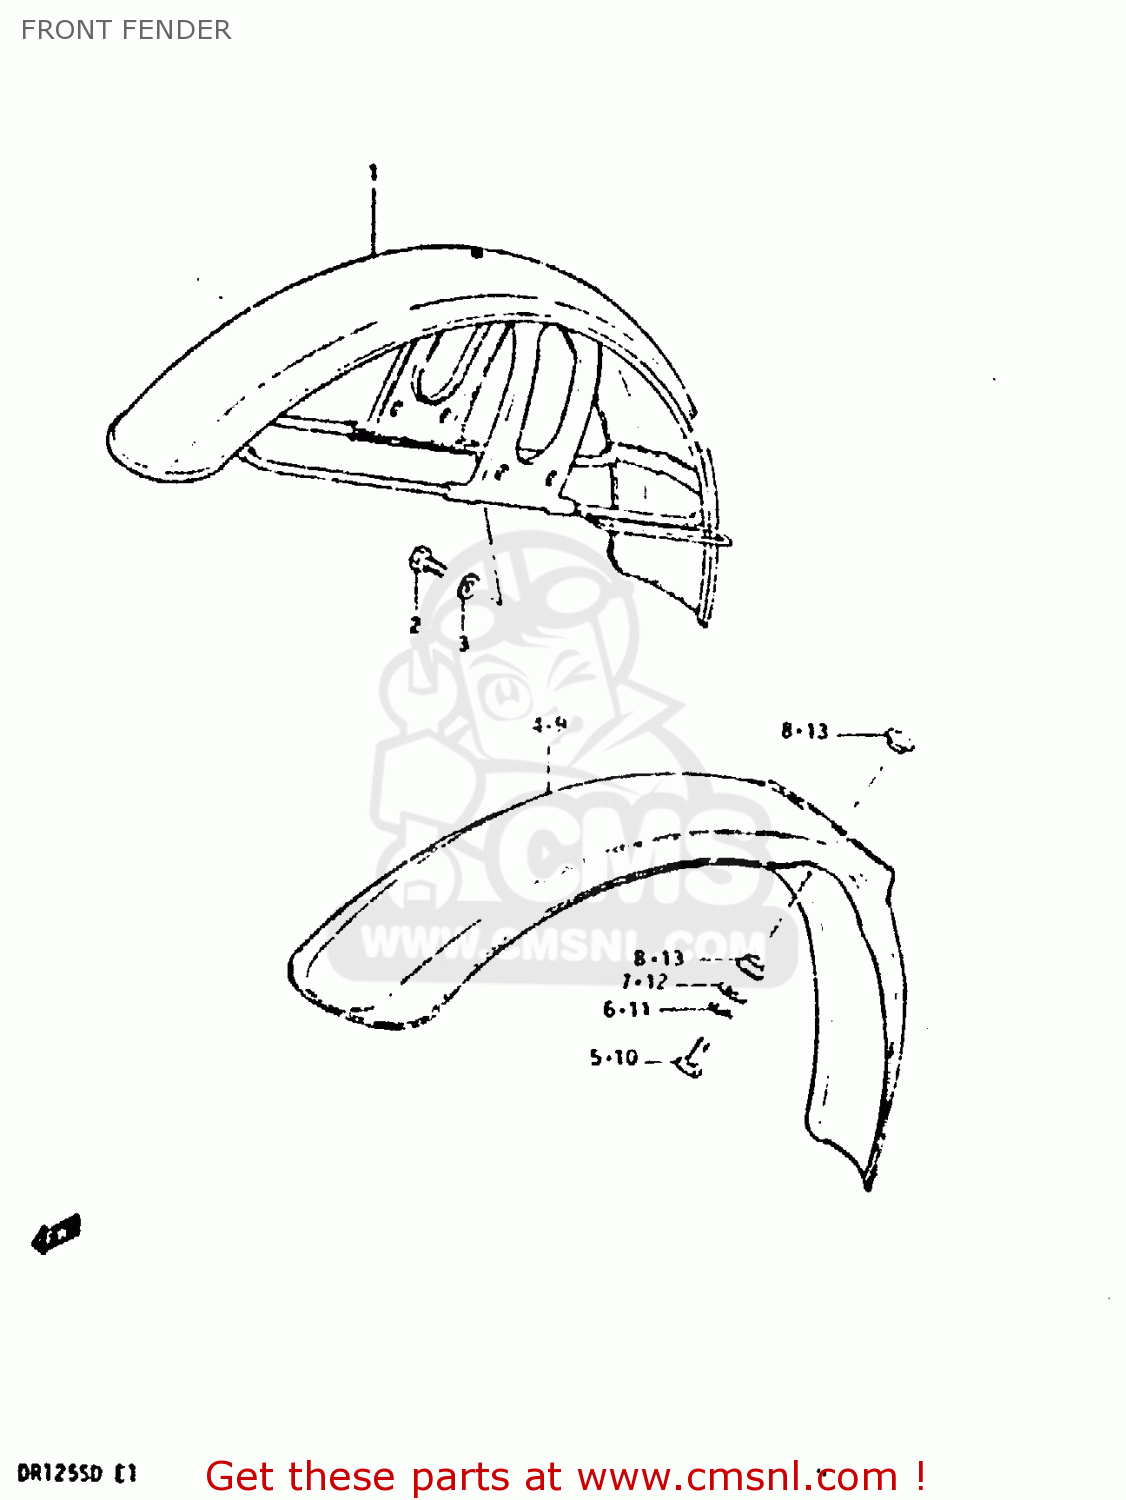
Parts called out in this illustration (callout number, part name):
1	FENDER,FR
2	BOLT
3	LOCK WASHER
4	FENDER, FRONT (BLUE)
5	BOLT, UPPER
6	LOCK WASHER
7	WASHER
8	SPACER
9	FENDER, FRONT (RED)
10	BOLT, UPPER
11	LOCK WASHER
12	WASHER
13	SPACER
